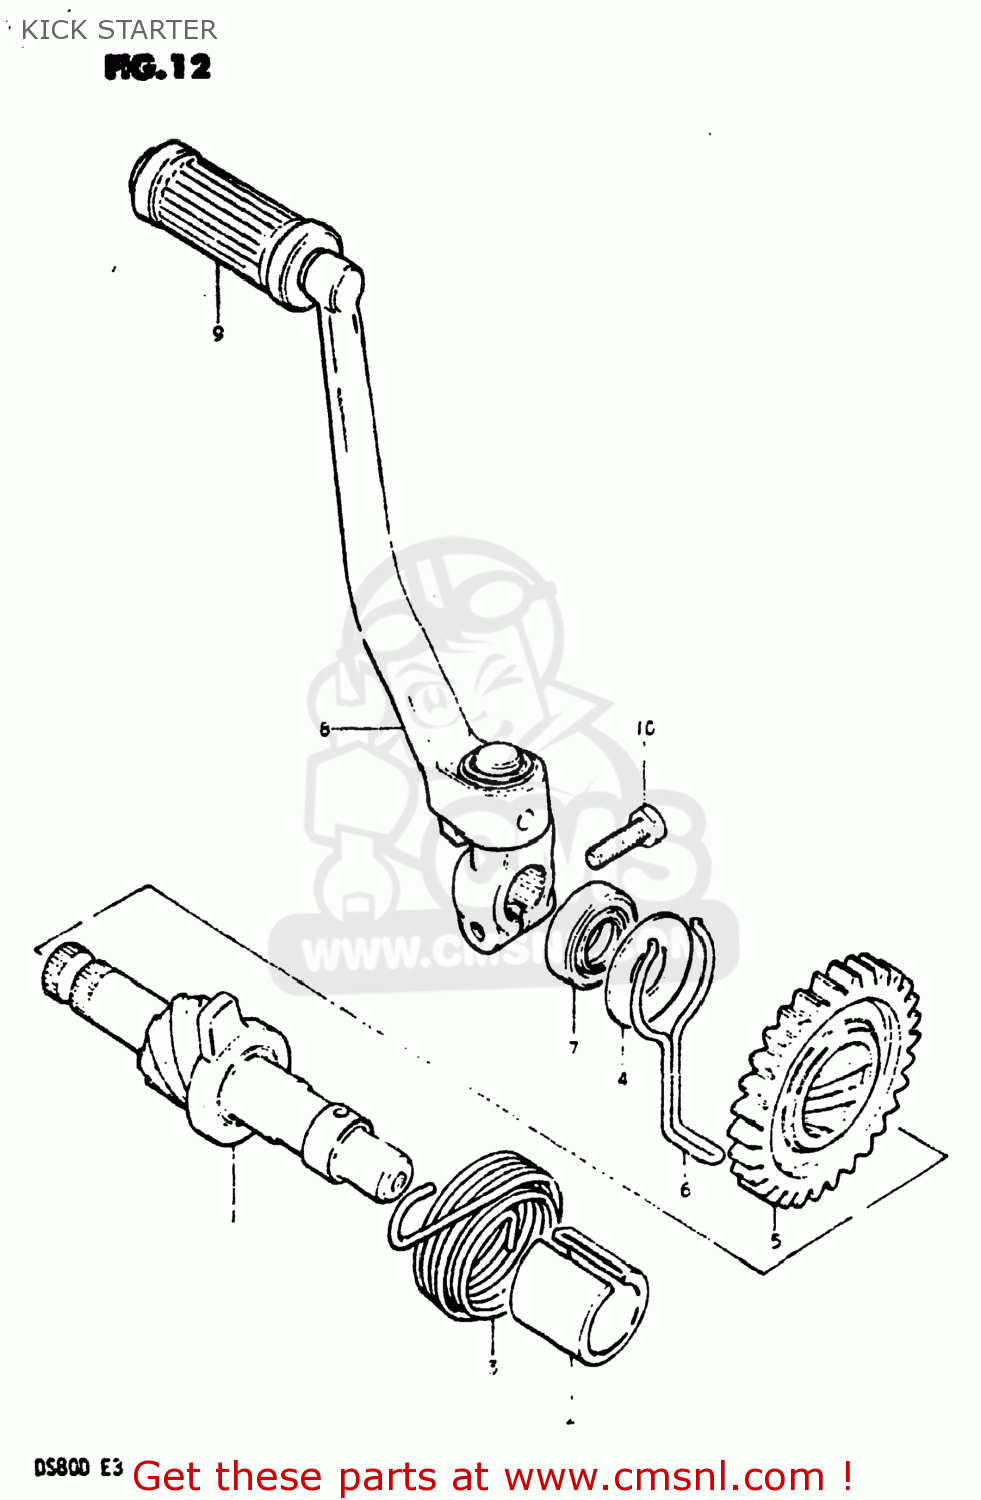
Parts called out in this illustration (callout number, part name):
1	SHAFT,KICK STARTER
2	GUIDE,KICK STARTER SFT SPRING
3	SPRING
4	WASHER
5	GEAR,KICK STARTER DRIVE(NT:30)
6	RETAINER,SNAP
7	SEAL,OIL(14X24X6)
8	LEVER ASSEMBLY,KICK STARTER
9	RUBBER,KICK STARTER PEDAL
10	BOLT
